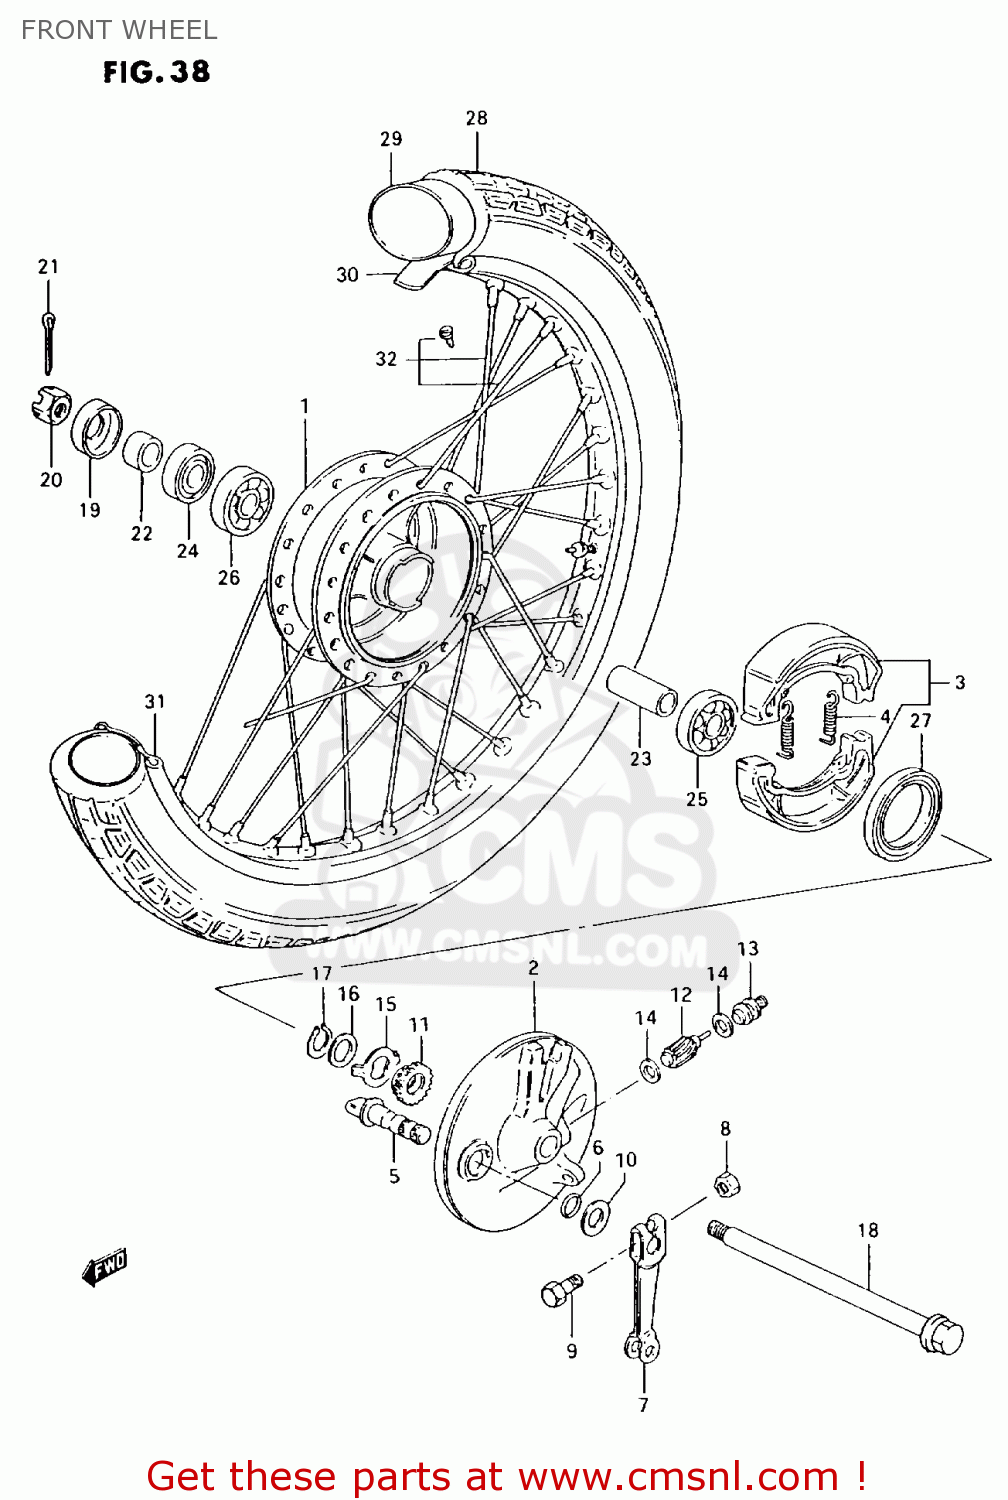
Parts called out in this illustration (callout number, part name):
1	HUB,FR WHEEL
2	PANEL,FR BRAKE ANCHOR
3	SHOE & SPRING SET,BRAKE (NAS)
4	SPRING
5	CAM,BRAKE
6	O-RING (D:2.4 ID:13.8)
7	LEVER,FR BRAKE CAM
8	NUT
9	BOLT(6X32)
10	WASHER (14.5X22X1.6)
11	GEAR,SPEEDOMETER(NT:26)
12	GEAR,SPEEDOMETER
13	BUSH,SPEEDOMETER PINION OUTER
14	WASHER (5.1X9X0.4)
15	DRIVER,SPEEDOMETER GEAR
16	WASHER(16X22X1)
17	CIRCLIP
18	AXLE,FR
19	COVER,FRONT HUB DUST S
20	NUT
21	PIN 20X20
22	SPACER(10X15X12.4)
23	SPACER (10.2X16X51)
24	SEAL,OIL(15X31X5)
25	BEARING
26	BEARING
27	OIL SEAL (43X58X7)
28	TIRE,FR(2.50-18 40L NF2)
29	TUBE,INNER
30	PROTECTOR,INNER TUBE
31	RIM,WHEEL(1.40X18)
32	SPOKE SET,FR
